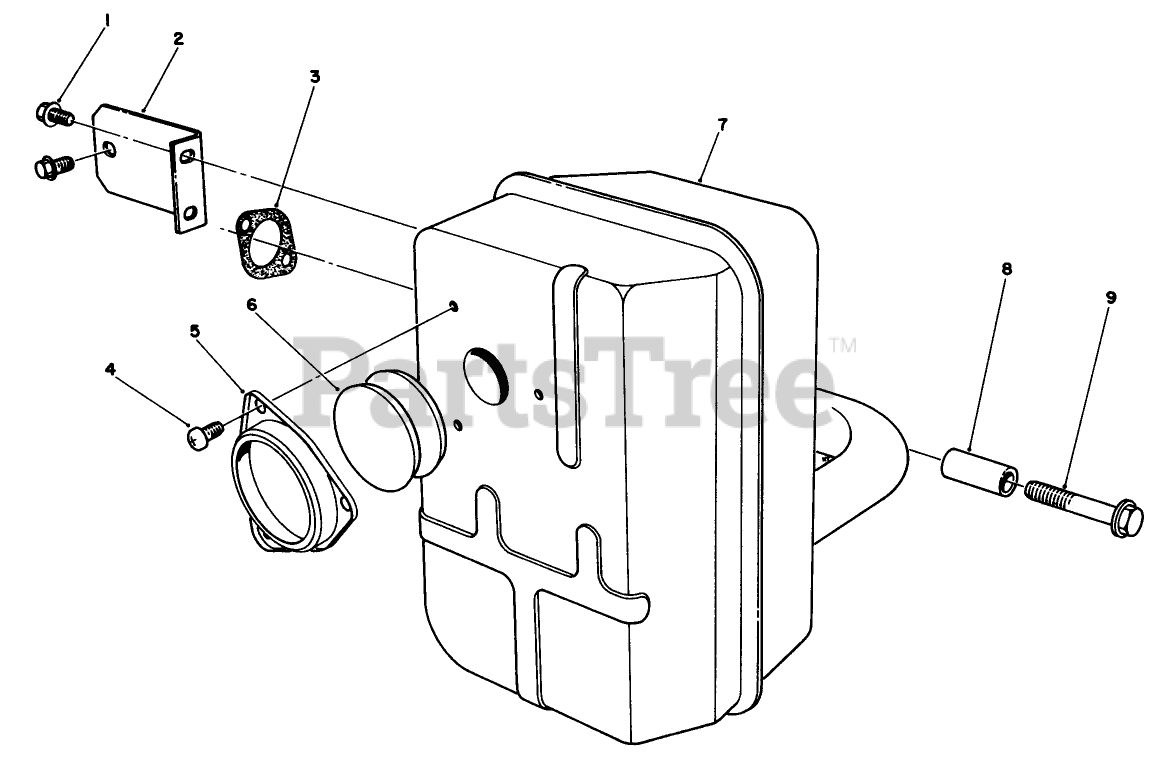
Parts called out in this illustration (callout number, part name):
1	Bolt-Flanged (8X12)
6	Arrester-Spark
7	Muffler Assembly (Incl. Ref.# 4,5 6)
9	Bolt-Flanged (8X45)
